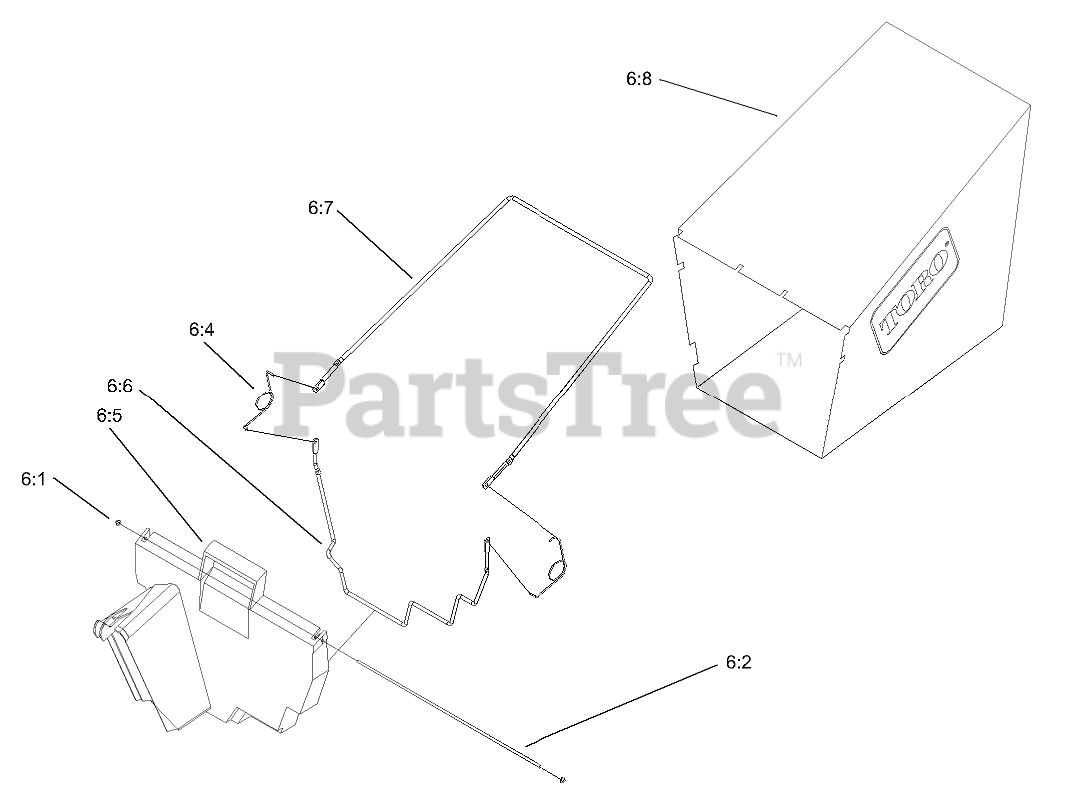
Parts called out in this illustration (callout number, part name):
6	Grass Bag ASM
6:1	NUT-PUSH
6:2	HINGE-DOOR, BAG
6:4	SPRING
6:5	DOOR-BAG
6:6	FRAME-BAG
6:7	FRAME-BAG, UPPER
6:8	BAG-GRASS
